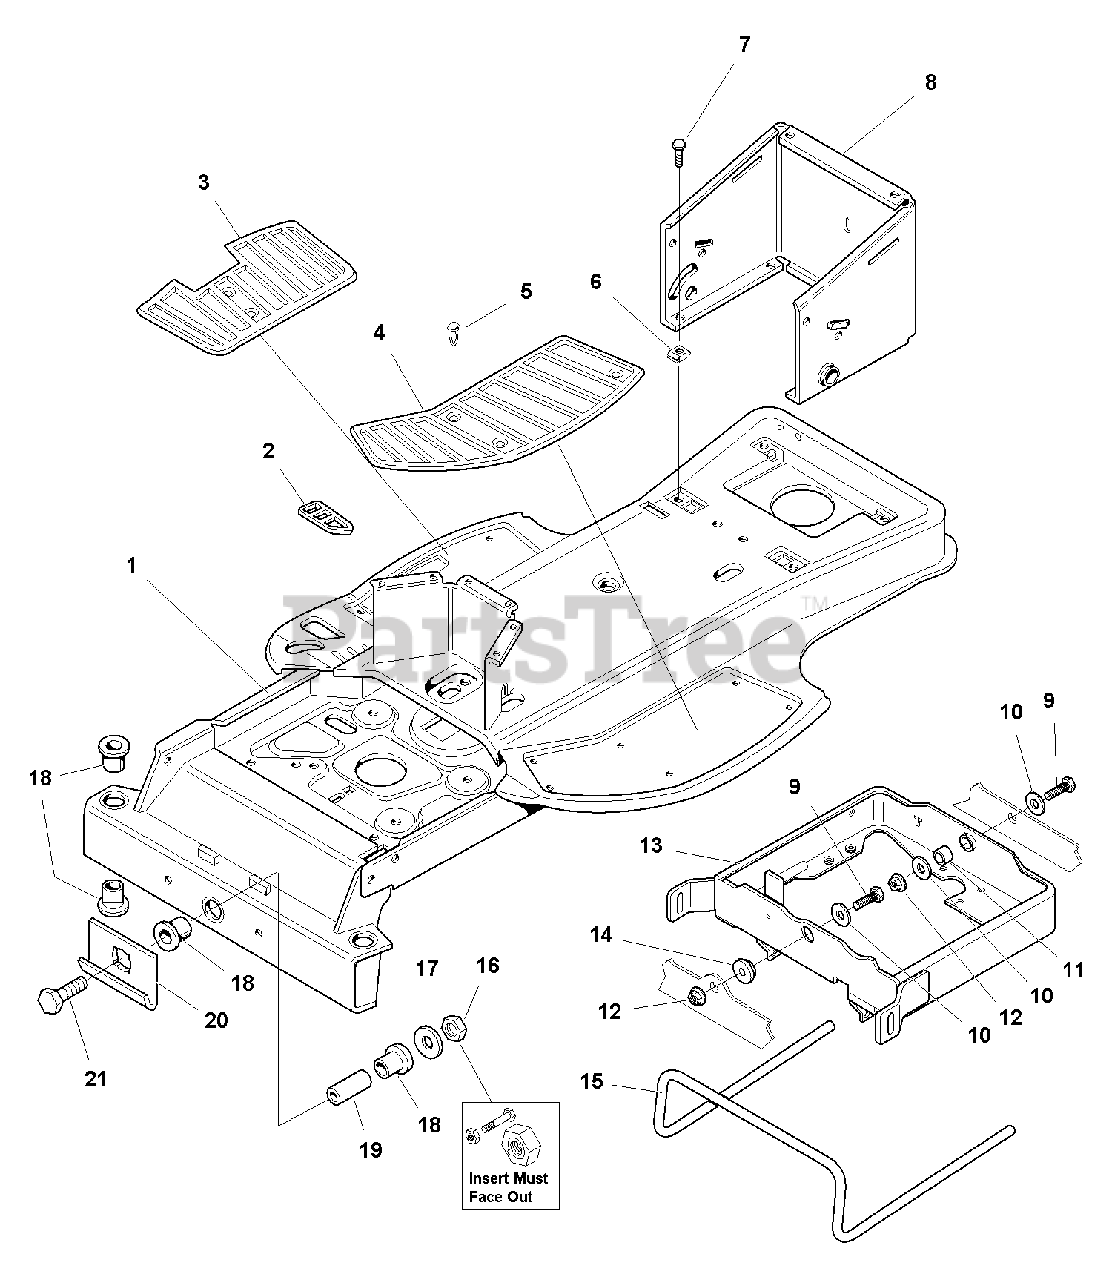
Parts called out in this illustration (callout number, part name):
1	FRAME ASSEMBLY
3	PAD, Footrest RH
4	PAD, Footrest LH
5	FASTENER, Panel
6	NUT, Speed 5/16-18
7	CAPSCREW, Hex Head Flange Lock, 5/16-18 x 3/4
8	WRAPPER ASSEMBLY, Hydro
9	CAPSCREW, Hex Head, 1/2-13 x 1-1/2
10	WASHER, 1/2
12	NUT, Hex Head, 1/2-13
13	CARRIER ASSEMBLY, Hydro
15	BAR, Torsion
16	NUT, Hex Head Aluminum Insert, 3/8-16
17	WASHER, 3/8
18	BUSHING, 3/4, Nylon
20	"J" HOOK, Hitch
21	CAPSCREW, Hex Head, 3/8-16 x 3, G8
